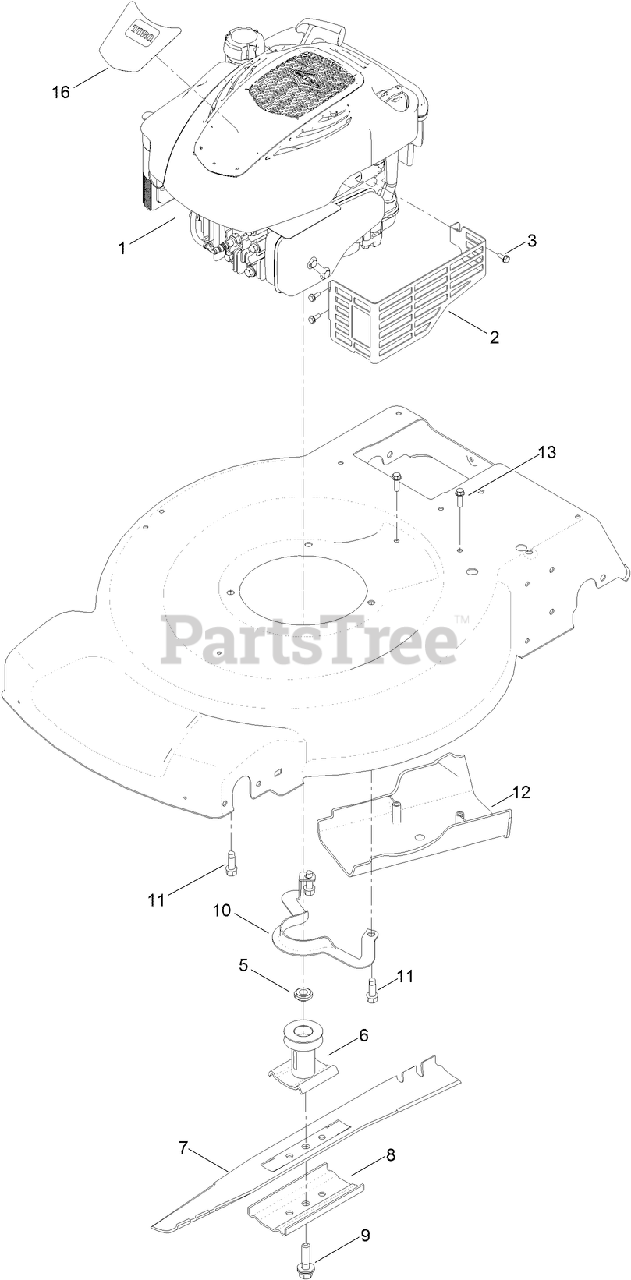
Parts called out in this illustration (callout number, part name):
2	SHIELD-MUFFLER
3	SCREW-TAPTITE
5	SPACER-DRIVER
6	DRIVER-BLADE
8	ACCELERATOR-BLADE
9	BOLT-BLADE
10	GUIDE-BELT
11	SCREW-TAPTITE
12	COVER-BELT
13	SCREW-HWH
16	DECAL-SHROUD
